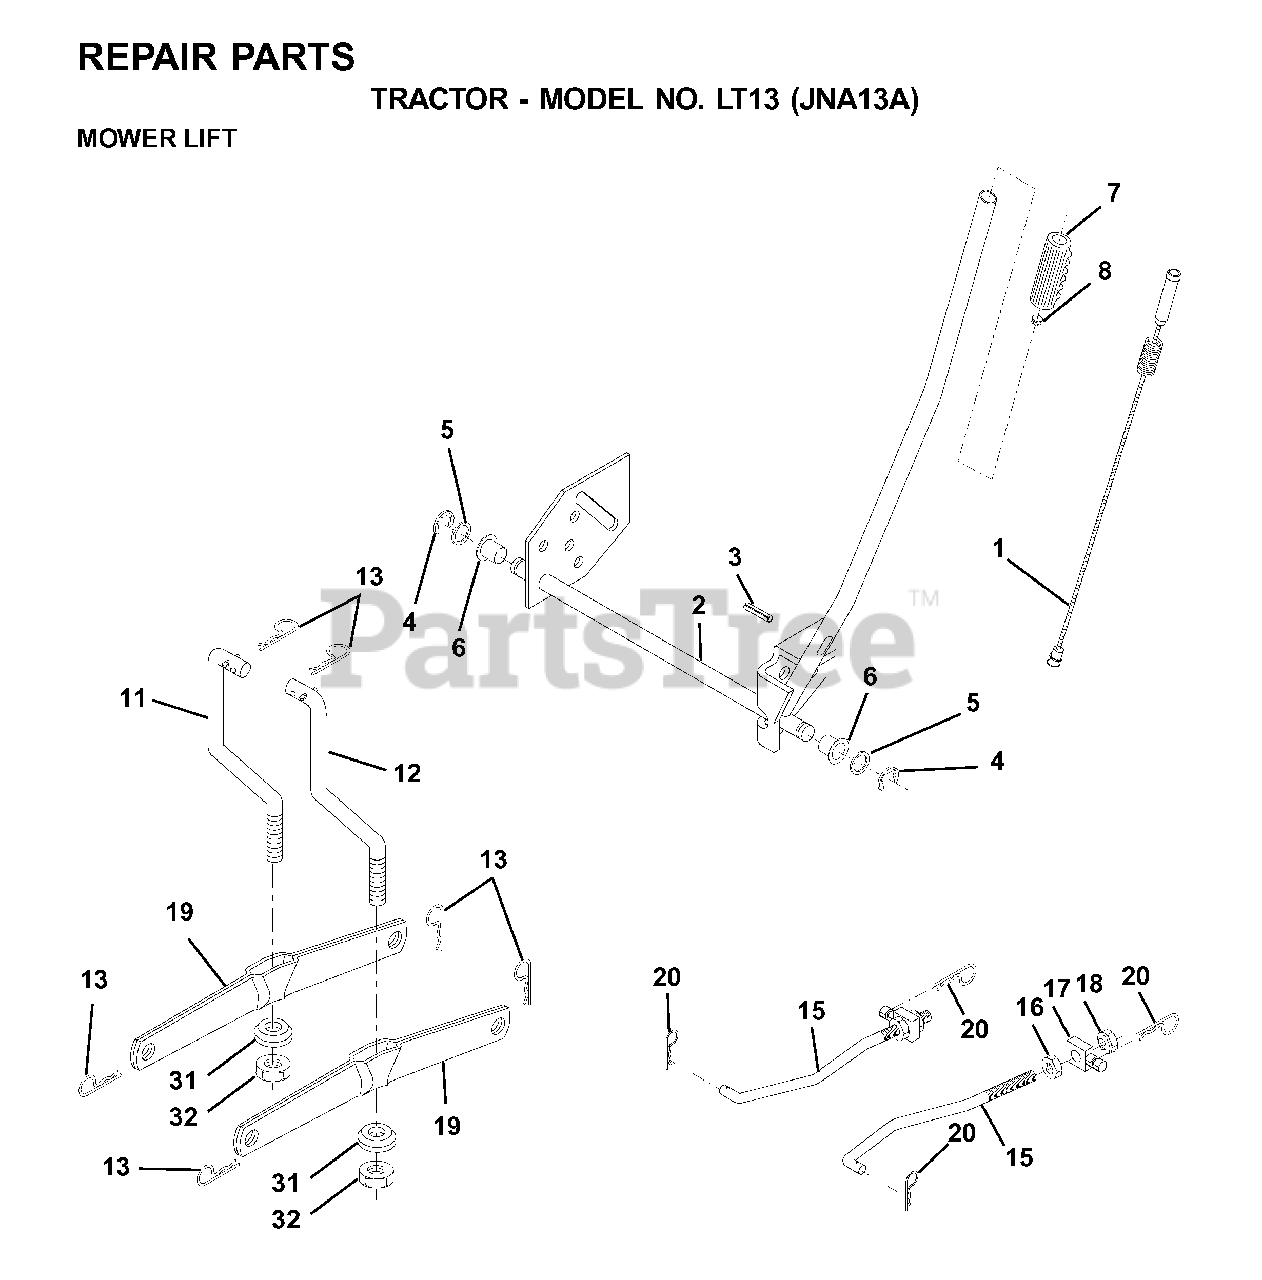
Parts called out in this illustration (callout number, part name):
1	WIRE ASM INNER W/ PLUNGER LT
2	SHAFT ASM R HANDLE
3	PIN GROOVE
4	RETAINING RING LT
6	BEARING.NYLON
7	GRIP
8	PLUNGER BUT KIT
11	LINK LIFT LH
12	LINK LIFT RH
13	RETAINER-SPRNG RB
15	LINK.SUSPENSION.FRONT
16	NUT
17	TRUNION
18	NUT
19	ARM.REAR.SUSPENSION
20	SPRING RETAINER
31	BEARING.PIVOT.LIFT
32	NUT CROWNLOCK 3/8-24
